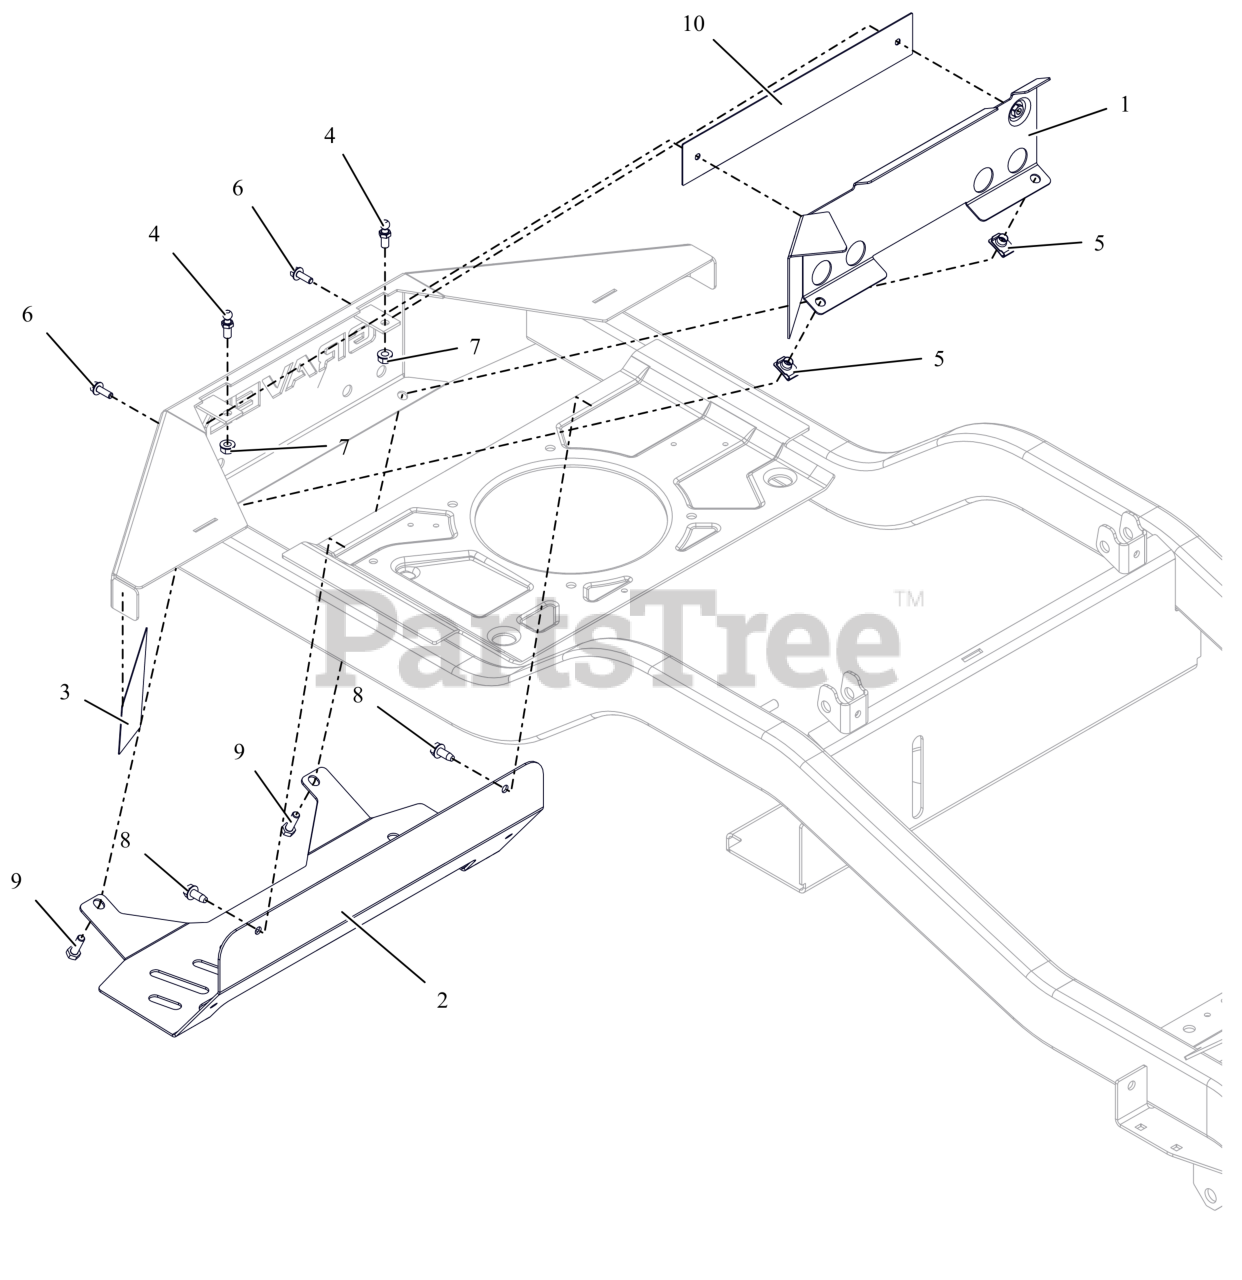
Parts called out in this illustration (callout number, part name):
1	WMT, HEAT BAFFLE
2	SHIELD, HEAT (HD)
3	TAPE, HEAT DEFLECTOR
4	STUD- BALL
5	NUT-CLIP RETAINER 5/16-18X.56
6	BLT,HEX-FLG .25-20X.75 G5 BFP
7	NUT,LK-CTR-FLG .31-18 GF ZCC
8	SCR,TAP .312-18X.75 HWH TR ZCC
9	BLT,HEX .31-18X1.00 G5 ZCC
10	PLATE- BACK BUMPER HD
